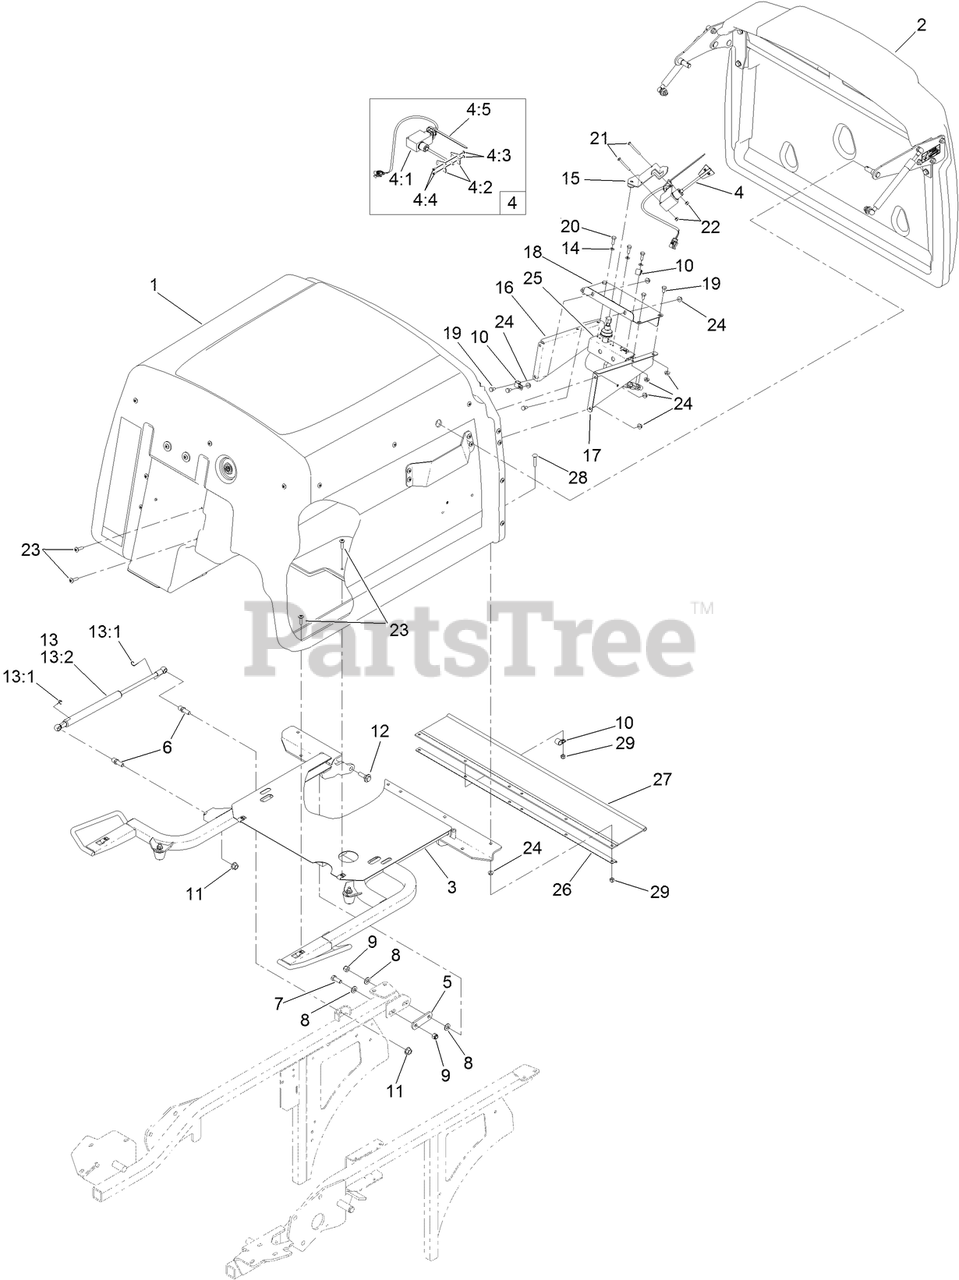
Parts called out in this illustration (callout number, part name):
1	HOPPER ASM
2	HOPPER DOOR ASM
3	HOPPER FRAME ASM
4	FILL SENSOR ASM
4:1	FILL SENSOR WIRE KIT
4:2	FLAG-SENSOR, FILL
4:3	NUT-HEX
4:4	SCREW-PAN
4:5	TIE-PLASTIC
5	ARM-LIFT, DECK
6	STUD-BALL
7	SCREW-HH
8	WASHER-FLAT
9	NUT-LOCK, NI
10	CLIP-LOOM
11	NUT-HF
12	SCREW-SHOULDER, HWH
13	DAMPER KIT
13:1	CLIP-RETAINER
13:2	SHOCK-COMPRESSION, GAS
14	WASHER-SPRING
15	MOUNT-SWITCH
16	BRACKET-DRIVE MOTOR, LH
17	BRACKET-DRIVE MOTOR, RH
18	PLATE-SWITCH
19	SCREW-HH
20	SCREW-HH
21	SCREW-PPH
22	NUT-LOCK, NI
23	SCREW-TTH
24	NUT-HF
25	MOTOR WIRING ASM
26	CHANNEL-FRAME, HOPPER
27	DEFLECTOR-GRASS
28	SCREW-CARR
29	NUT-LOCK, NI
